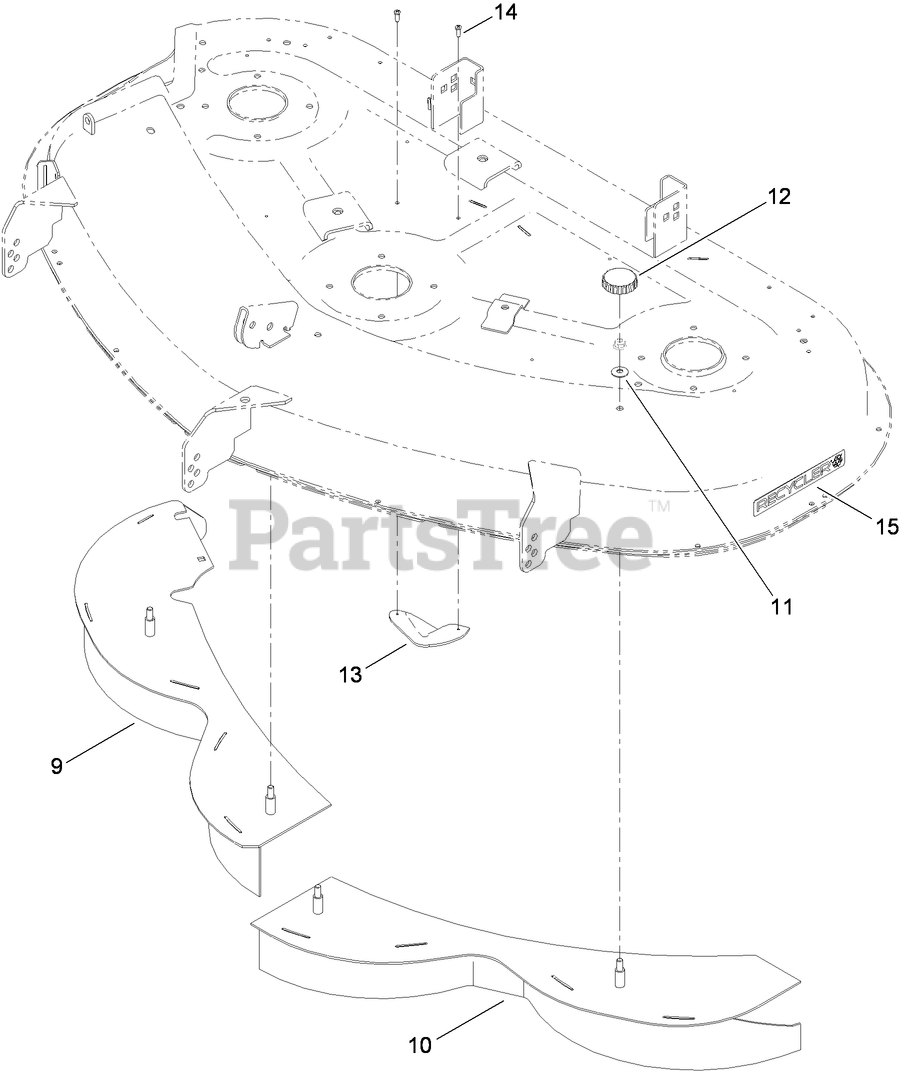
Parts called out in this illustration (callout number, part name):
9	RH BAFFLE ASM
10	LH BAFFLE ASM
11	WASHER-BELLEVILLE
13	PLATE-KICKER
14	SCREW-PPH
15	DECAL-RECYCLER
